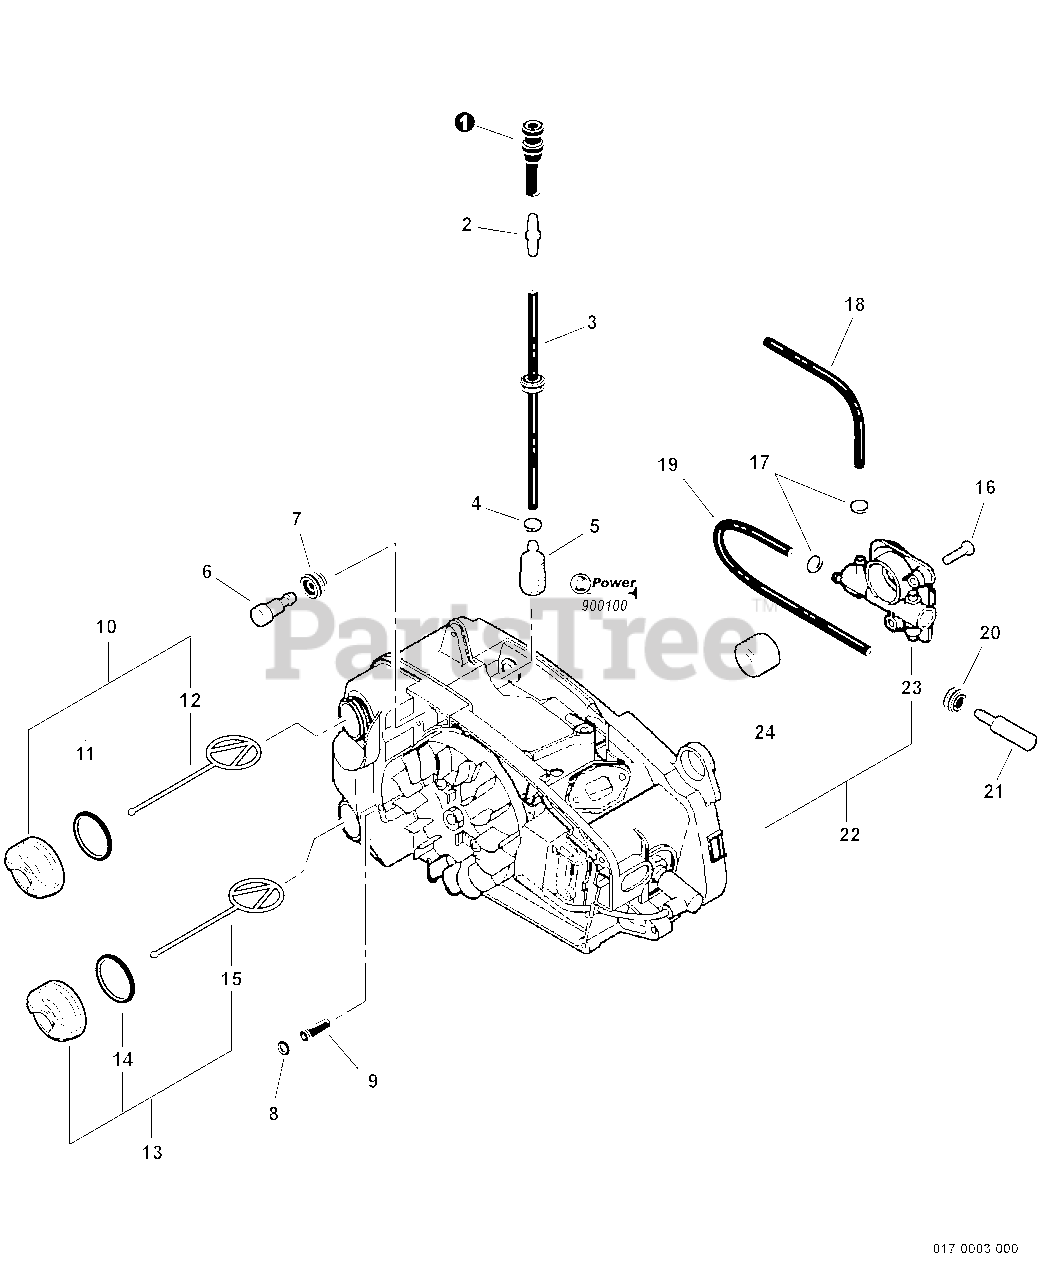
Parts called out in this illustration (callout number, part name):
1	PIPE - FUEL
2	CONNECTOR, PIPE
3	FUEL PIPE ASSY
4	CLIP - 6
5	FILTER, FUEL
6	VENT, FUEL TANK
7	GROMMET
8	O-RING - 4
9	VENT, TANK
10	CAP ASSY - ORANGE
11	O-RING - 18
12	CONNECTOR, CAP
13	CAP ASSY - BLACK
14	O-RING - 18
15	CONNECTOR, CAP
16	SCREW - 4X12
17	CLIP - 6.5
18	PIPE - 3X6X90 -- BLACK
19	PIPE - 3X5X195 -- BLACK
20	GROMMET
21	FILTER, OIL
22	AUTO-OILER ASSY
23	AUTO-OILER ASSY
24	GEAR - WORM
25	RePower TUNE-UP KIT
